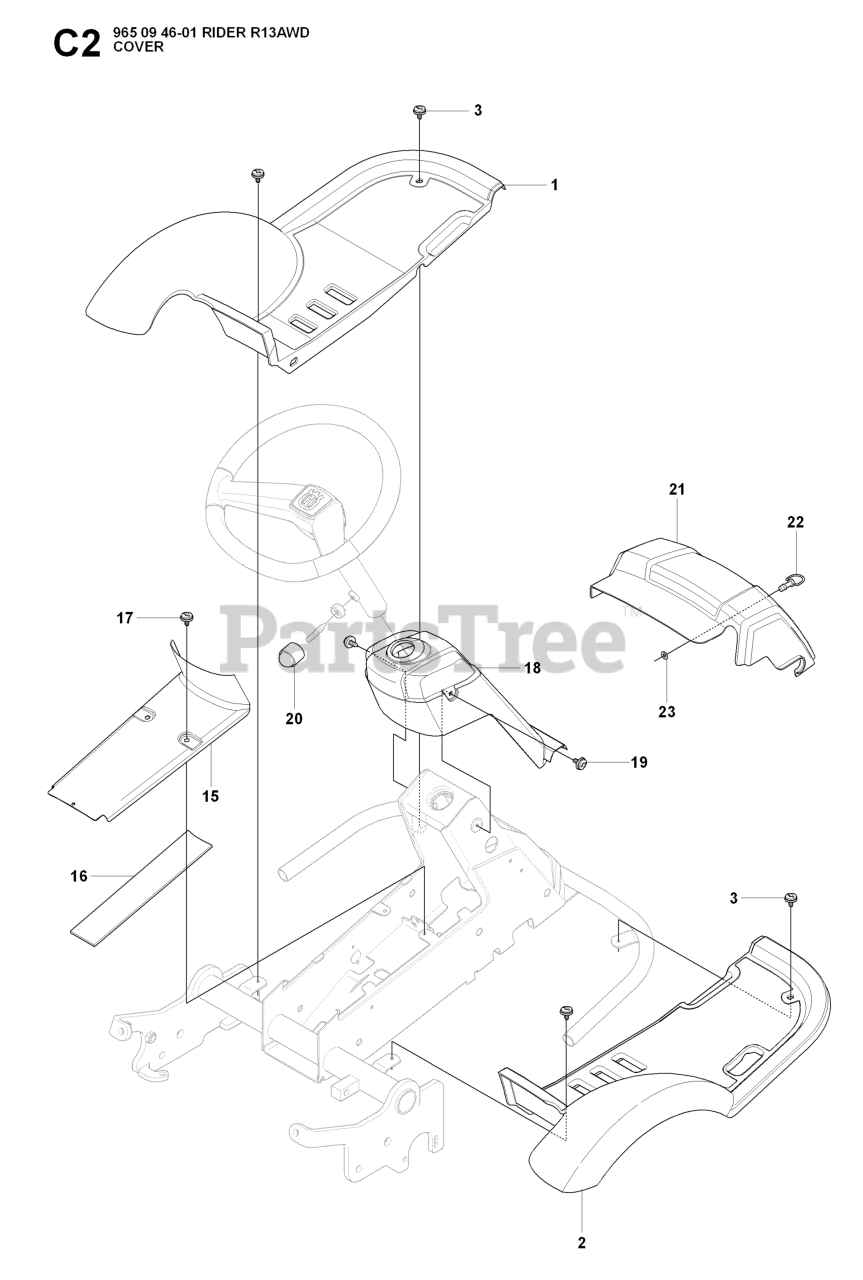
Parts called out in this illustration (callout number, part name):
1	FOOT PLATE
2	FOOT PLATE
20	PROTECTIVE COVER
22	BOLT
